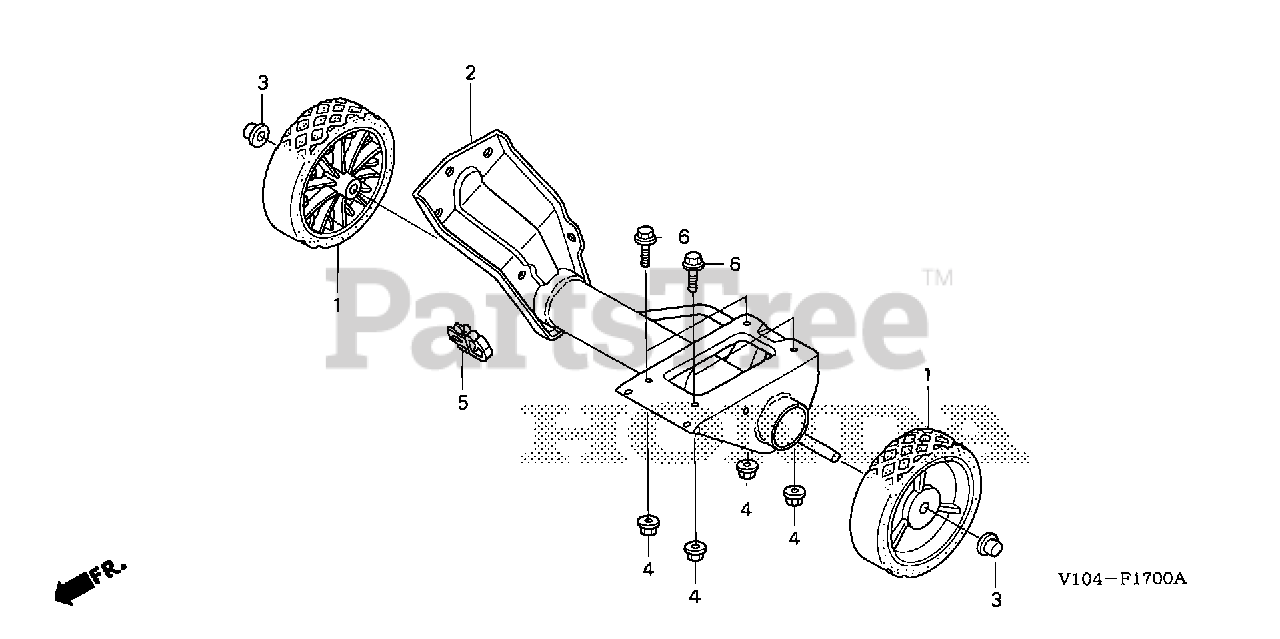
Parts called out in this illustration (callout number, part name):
1	WHEEL ASSY.
2	BED, ENGINE
3	NUT, PUSH (12.7MM)
4	NUT, FLANGE (8MM)
5	CLIP, HARNESS (5MM-15MM) (BLACK)
6	BOLT, FLANGE (8X35)
